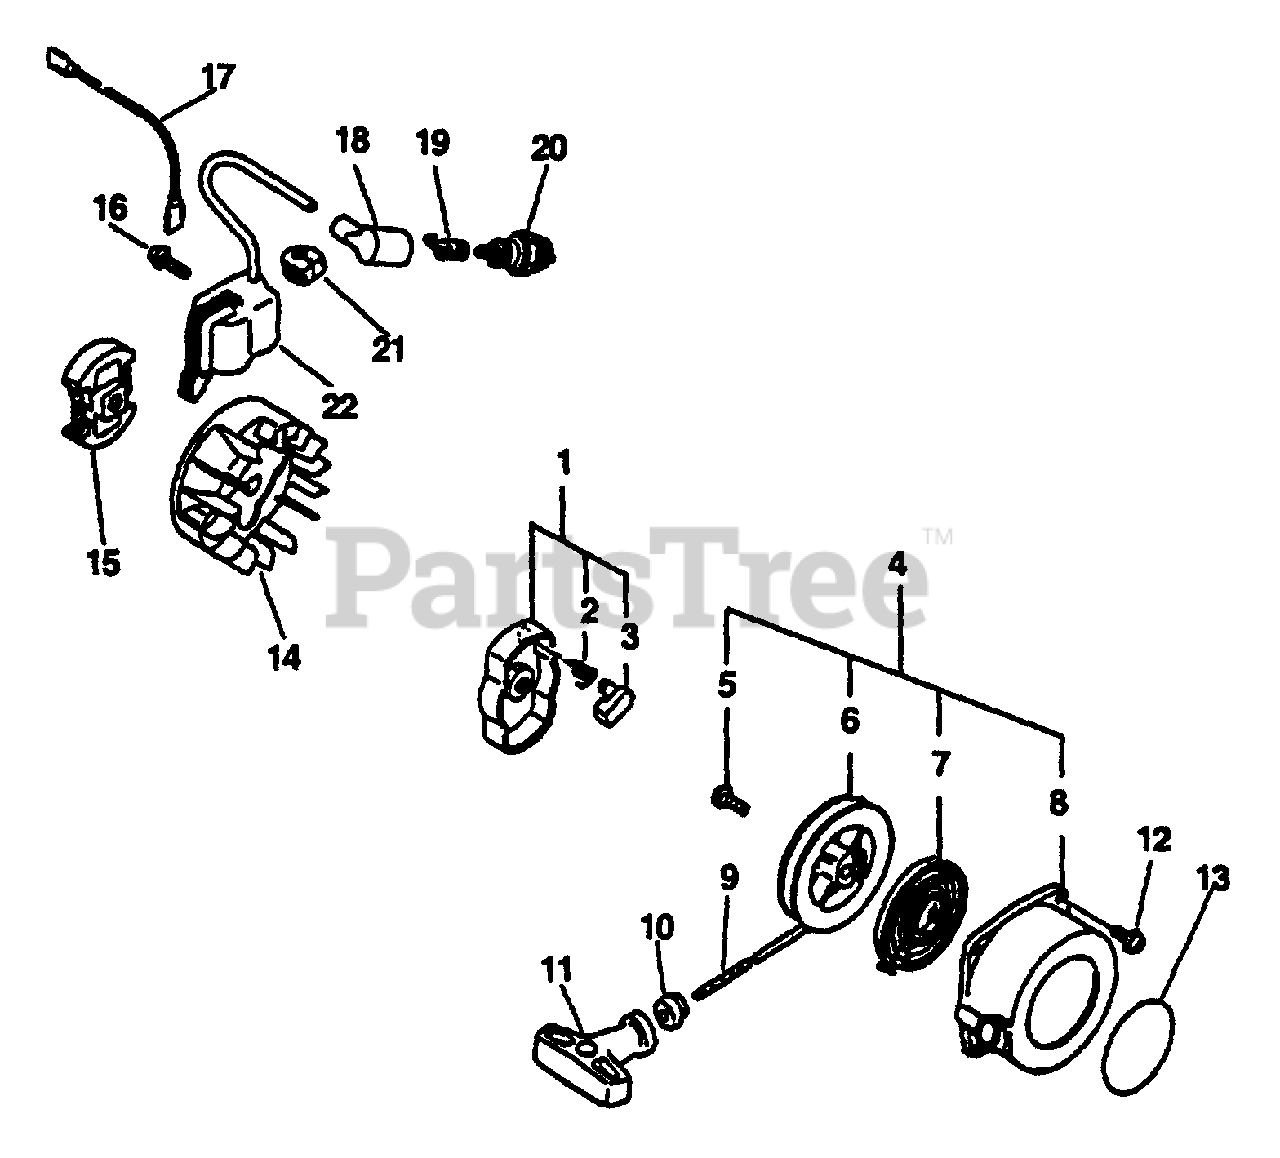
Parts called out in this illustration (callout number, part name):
1	STARTER PAWL ASSY
2	SPRING, RETURN
3	PAWL, STARTER - BLACK
4	STARTER ASSY
6	REEL, ROPE
7	SPRING, REWIND
8	CASE, STARTER
9	ROPE, STARTER - 3X1000
10	GUIDE, ROPE
11	GRIP, STARTER
12	SCREW - 4X16
13	LABEL - ECHO
14	FLYWHEEL
15	CLUTCH ASSY
16	SCREW - 4X22
17	LEAD - GROUND
18	CAP, SPARK PLUG
19	TERMINAL, SPARK PLUG CAP
20	SPARK PLUG -- BPM-7Y
20	SPARK PLUG -- BPMR-7A
22	COIL, IGNITION
